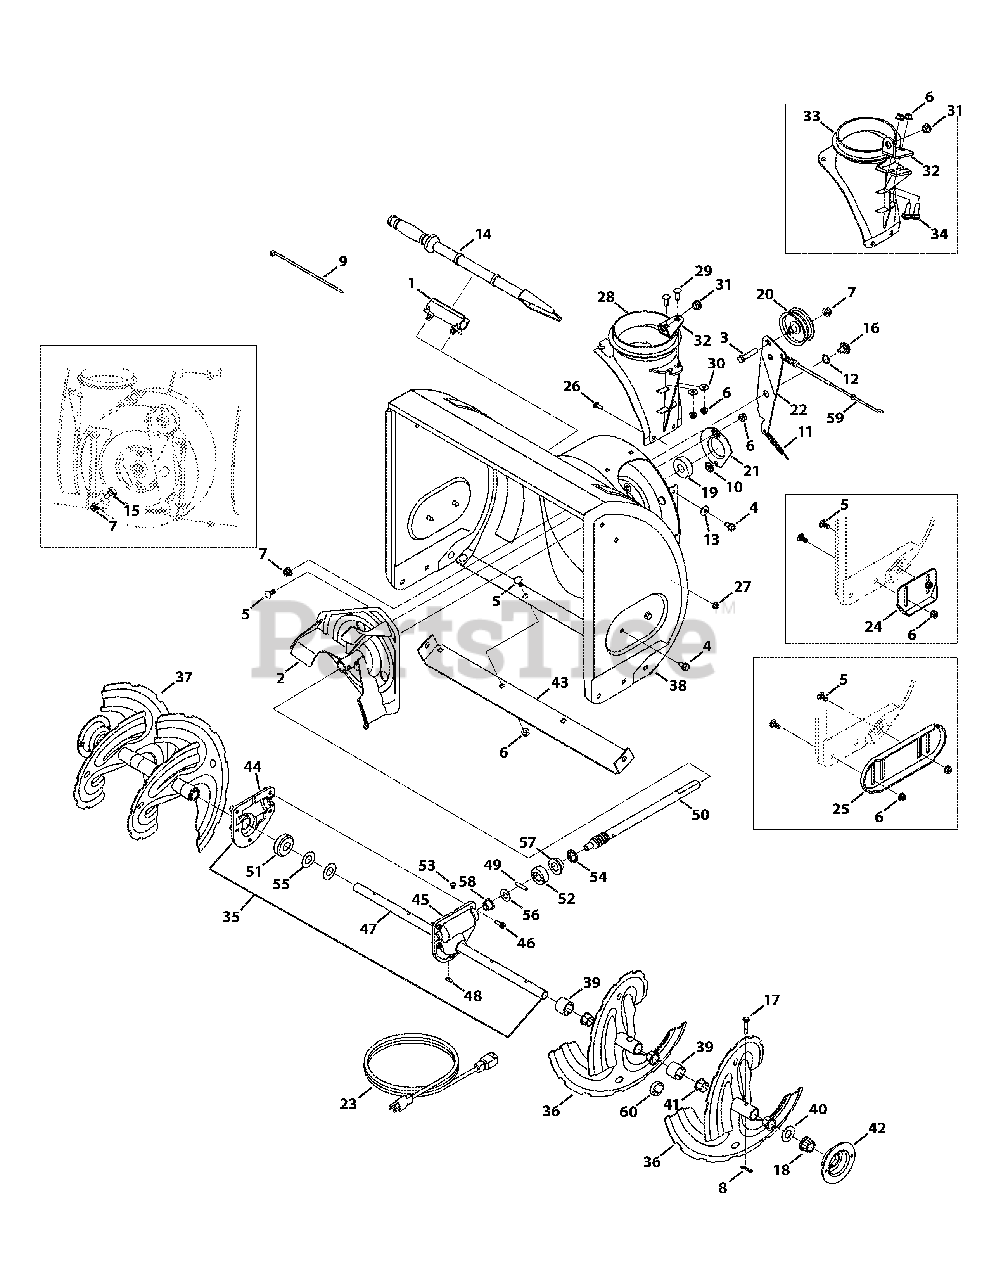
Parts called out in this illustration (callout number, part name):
1	Cleanout Tool Mount
2	Impeller Assembly, 12"
3	Hex Screw, 3.8-16 x 1.75
4	Hex Washer Screw, 5.16-18 x .750
5	Carriage Bolt, 5.16-18 x .750
6	Flange Lock Nut, 5.16-18
7	Flange Lock Nut, 3/8-16
8	Bow-Tie Cotter Pin
9	Cable Tie, 3.16 x .05 x 7.4
10	Push Nut, .25 Dia.
11	Extension Spring
12	Wave Washer, .625 x .885 x .015
13	Bell Washer, .340 x .872 x .060
14	Chute Cleanout Tool
15	Shoulder Bolt, .496 x .336 x 3.8-16
16	Shoulder Screw, .625 x .17 x 3.8-16
17	Shear Pin, .25 x 1.50
18	Hex Flange Bearing, .75 ID
19	Ball Bearing, .75 ID x 1.85 OD
20	Idler Pulley, 2.75 OD
21	Bearing Housing, 1.85 ID
22	Auger Idler Bracket
23	Extension Cord (Electric Start Only)
24	Skid Shoe - Red
24	Skid Shoe - Black
25	Deluxe Skid Shoe - Red
25	Deluxe Skid Shoe - Black
26	Carriage Screw, 1.4-20 x .75
27	Flange Lock Nut, 1/4-20
28	Chute Adapter, 5"
29	Carriage Screw, 5/16-18 x 1.00
30	Flat Washer, .349 x .879 x .063
31	Plastic Bushing, .380 ID
32	Chute Crank Bracket
33	Chute Crank Bracket, Big Block Engine
34	Carriage Bolt, 5.16-18 x 1.00
35	Gearbox Assembly, 24"
35	Gearbox Assembly, 26"
35	Gearbox Assembly, 28"
35	Gearbox Assembly, 30"
36	Spiral Assembly, LH - Black
36	Spiral Assembly, LH - Red
36	Spiral Assembly, LH - Grey
37	Spiral Assembly, RH - Black
37	Spiral Assembly, RH - Red
37	Spiral Assembly, RH - Grey
38	Auger Housing Assembly, 24" - Red
38	Auger Housing Assembly, 24" - Black
38	Auger Housing Assembly, 26" - Red
38	Auger Housing Assembly, 26" - Black
38	Auger Housing Assembly, 28" - Red
38	Auger Housing Assembly, 28" - Black
38	Auger Housing Assembly, 30"
39	Spacer, 1.2500 x .75 ID x 1.00 LG
40	Flat Washer, .76 x 1.49 x .06
41	Flange Bushing, .800 ID x .910 OD
42	Bearing Housing, 1"
43	Shave Plate, 24" - Red
43	Shave Plate, 24" - Black
43	Shave Plate, 26" - Red
43	Shave Plate, 26" - Black
43	Shave Plate, 28" - Red
43	Shave Plate, 28" - Black
43	Shave Plate, 30" - Red
44	Housing Assembly, RH
45	Housing Assembly, LH
46	Hex Washer Screw, 1.4-20 x .750
47	Auger Axle, 24"
47	Auger Axle, 26"
47	Auger Axle, 28"
47	Auger Axle, 30"
48	Hi-Pro Key
49	Dowel Pin, .25 OD x 1.25 LG
50	Worm Shaft, .75 OD
51	Worm Gear 2OT, 24" & 26"
51	Worm Gear 2OT, 28"& 30"
52	Thrust Collar, .756 ID x .600
53	Plug, 1.4 x .437
54	Oil Seal, .75 x 1.131 x .188
55	Flat Washer, .760 ID x 1.50 ID
56	Flat Washer, .51 x 1.12 x .06
57	Flng. Bearing, .75 ID x 1.00 OD x .59
58	Flange Bearing, .50 ID x .75 OD x .59
59	Auger Drive Cable
60	Spacer, 1.250 x .75 ID x 3.16 LG
